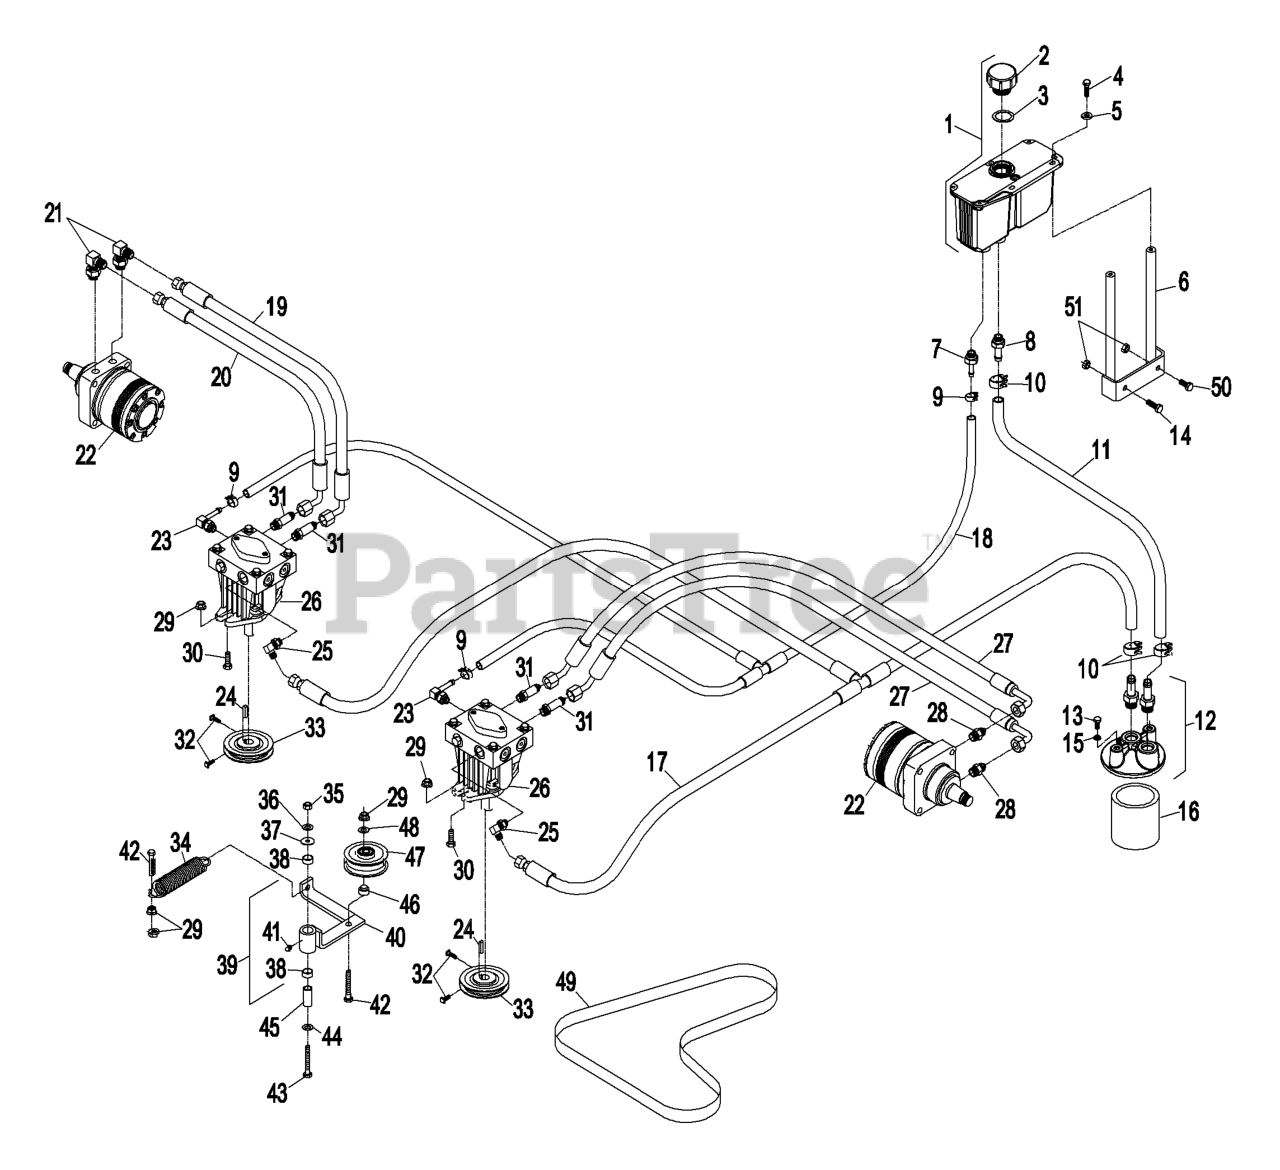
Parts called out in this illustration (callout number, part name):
1	HYD RESERVOIR ASM
2	Cap-Reservoir, HYD
3	GASKET-CAP
4	SCREW-HH
5	WASHER-FLAT
6	STAND-RESERVOIR
7	ADAPTER-STRAIGHT
8	ADAPTER-STRAIGHT
9	CLAMP-HOSE
10	CLAMP-HOSE
11	HYD HOSE ASM
12	FILTER HEAD ASM
13	SCREW-HH
14	SCREW-HH
15	WASHER-LOCK
17	HYD HOSE ASM
18	HYD HOSE ASM
19	HOSE-REAR, RH
20	HOSE-FRONT
21	FITTING-HYD, 90 DEG
22	MOTOR-WHEEL
23	ELBOW-90 DEG
25	FITTING-ELBOW, 90 DEG
26	PUMP-HYD
27	HOSE-LH
28	FITTING-STRAIGHT
29	NUT-HHF, WHIZ
30	SCREW-HH
31	ADAPTER-STR, LONG
32	SCREW-SET
34	SPRING-EXTENSION
35	NUT-LOCK, NI
36	WASHER-BELLEVILLE
38	SLEEVE-BEARING
41	FITTING-GREASE, 90 DEG
42	SCREW-HH
43	SCREW-HH
44	WASHER-FLAT
45	BUSHING
46	BUSHING-IDLER
48	WASHER-FLAT
50	SCREW-HH
